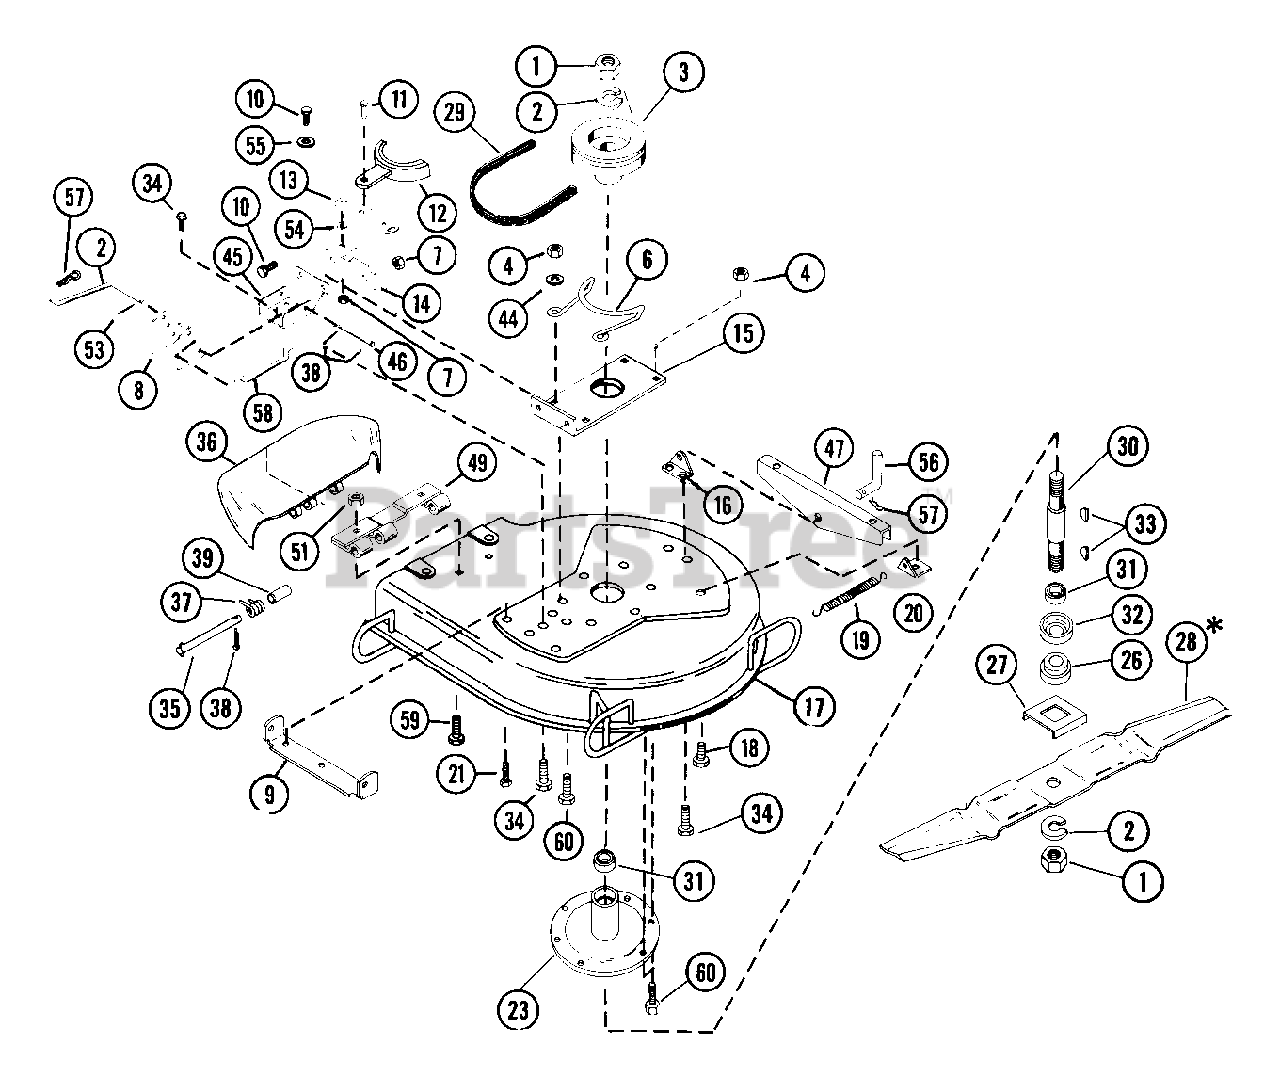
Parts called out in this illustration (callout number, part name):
1	NUT-JAM .75-10 PL
2	WSHR-LK .750X.188 MED PL
3	MOWER SHEAVE
4	NUT-LK-CTR .375-16 GR A PL
6	BELT FINGER
7	NUT-LK .312-18 GR A PL
8	MOWER ENGAGING ARM
9	FRONT MTG BRACKET
10	BLT-HEX .31-18X.63 PL GR 2
11	RVT .25X.50 RH ST
12	BLADE BRAKE
13	MOWER BRAKE LEVER
14	BRAKE BRACKET
16	REAR MTG BRACKET
17	26 IN MOWER PAN W/ DECALS
18	BLT-SERHFWH .25-20X.50 PL
19	SG-TENS .072X.51X5.31 WLD 25
20	BRAKE CLIP
21	BLT-SCRHFWH .38-16X.50 PL
22	BLT-HEX .31-18X.50 PL GR2
23	SPINDLE HOUSING
26	RETAINER HUB
27	BLADE TRAY
28	MOWER BLADE 26
29	V-BELT, 4L-WRAPPED
30	MOWER SPINDLE
31	BRG-BALL .750X1.781X.61
32	BEARING SLINGER
33	KEY-WDRF .188X.75X.313 SAE 9
34	BLT-SERHFWH .31-18X.50 PL
35	CLEVIS PIN
36	PAN CHUTE EXTENSION
37	SG-TORS .095X.50X 1.0
38	PIN-COTR .09X.75 PL
39	BSHG-SLV .334 X .502 X 1.437
40	LEAF MULCHER KIT-EMPEROR
42	WSHR-FL-STL .38X.875X.083 PL
43	MULCHER BRACKET
44	WSHR-FL-STL .406X.865X.094 PL
45	PIVOT BRACKET
46	PIN-CLEV .309X3.50 SP
47	SWIVEL BRACKET
49	HINGE PLATE
51	NUT-LK-CTR .250-20 PL
52	MOWER ENGAGEMENT LINK
53	PIN-COTR .12X.75 PL
54	SPACER
55	WSHR-FL-STL .328X1.0X.094
56	CLEVIS PIN
57	PIN-HAIR INT .08X.38X1.42 YWZC
58	MOWER BRAKE LINK
59	BLT-RDHDSQNK .25-20X.50 SHT PL
60	BLT-HEX .38-16X1.00 PL
